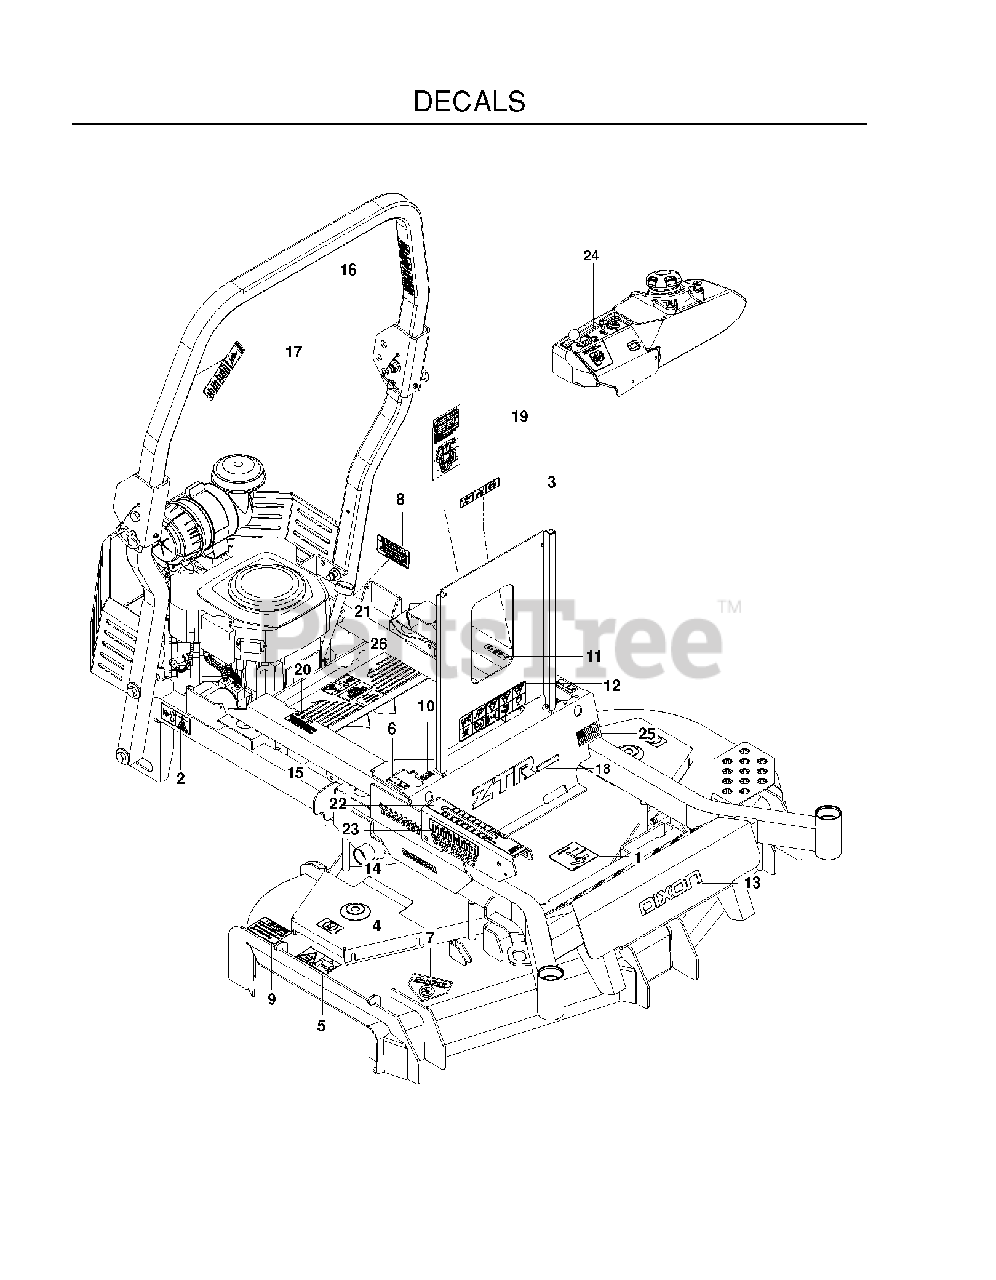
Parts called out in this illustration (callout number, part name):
1	DECAL, BELT ROUTING
2	DECAL, BELT DRIVE
3	DECAL, BATTERY
4	DECAL, NO STEP
5	DECAL, EURO SEVERING
7	DECAL, CPSC
8	DECAL, PROP. 65
9	DECAL, CAUTION
10	DECAL, TRACKING
11	DECAL, PARK BRAKE
12	DECAL, WARNING
14	DECAL, COMMERCIAL
15	DECAL, FUSE
17	DECAL, ROPS, WARNING
19	DECAL, SERVICE
20	DECAL, WARNING SPARK ARRESTOR
25	DECAL, FLAG
26	DECAL, OIL TANK
